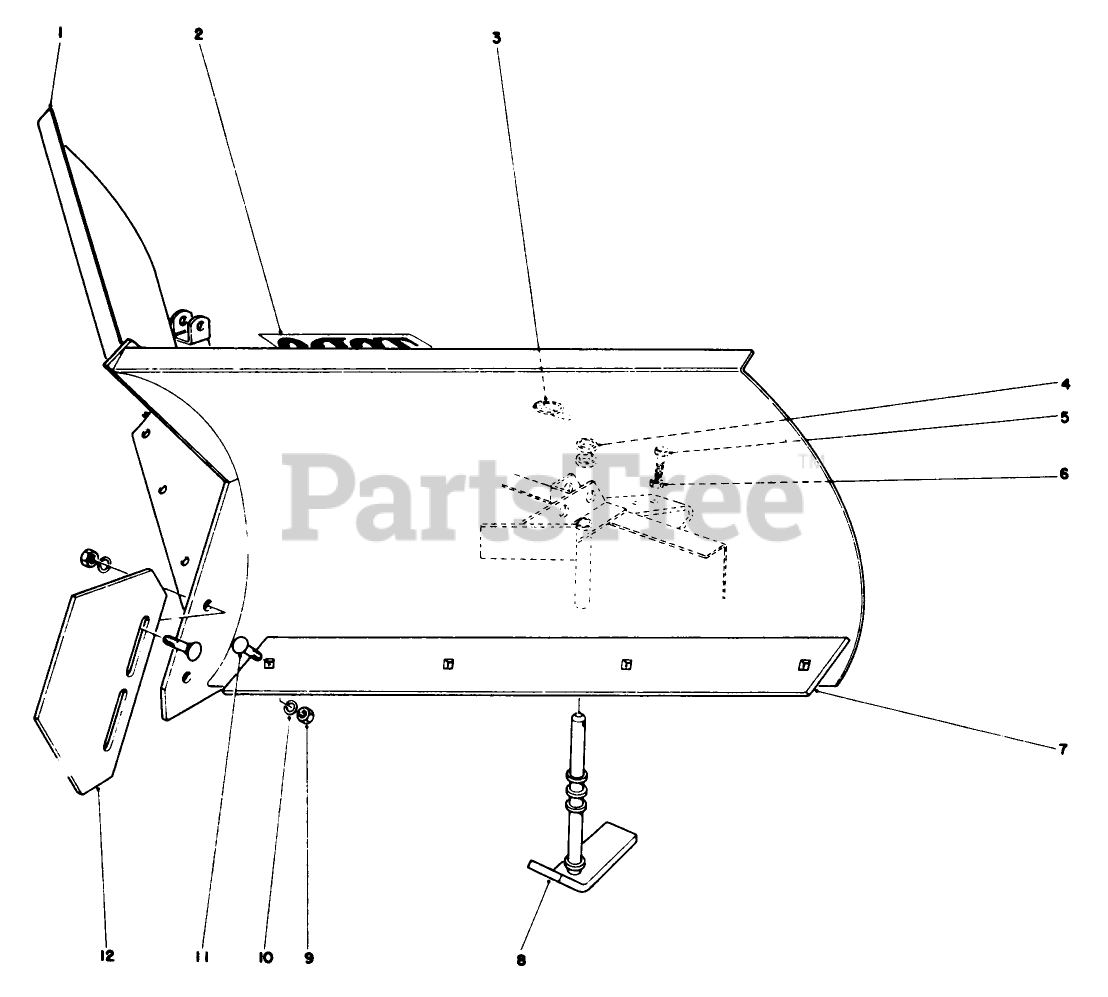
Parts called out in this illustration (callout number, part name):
3	PIN-LYNCH
4	SPACER-TUBULAR
5	SCREW-HH
6	NUT-JAM
9	NUT-HH
10	SCREW-HH
11	SCREW-HH
